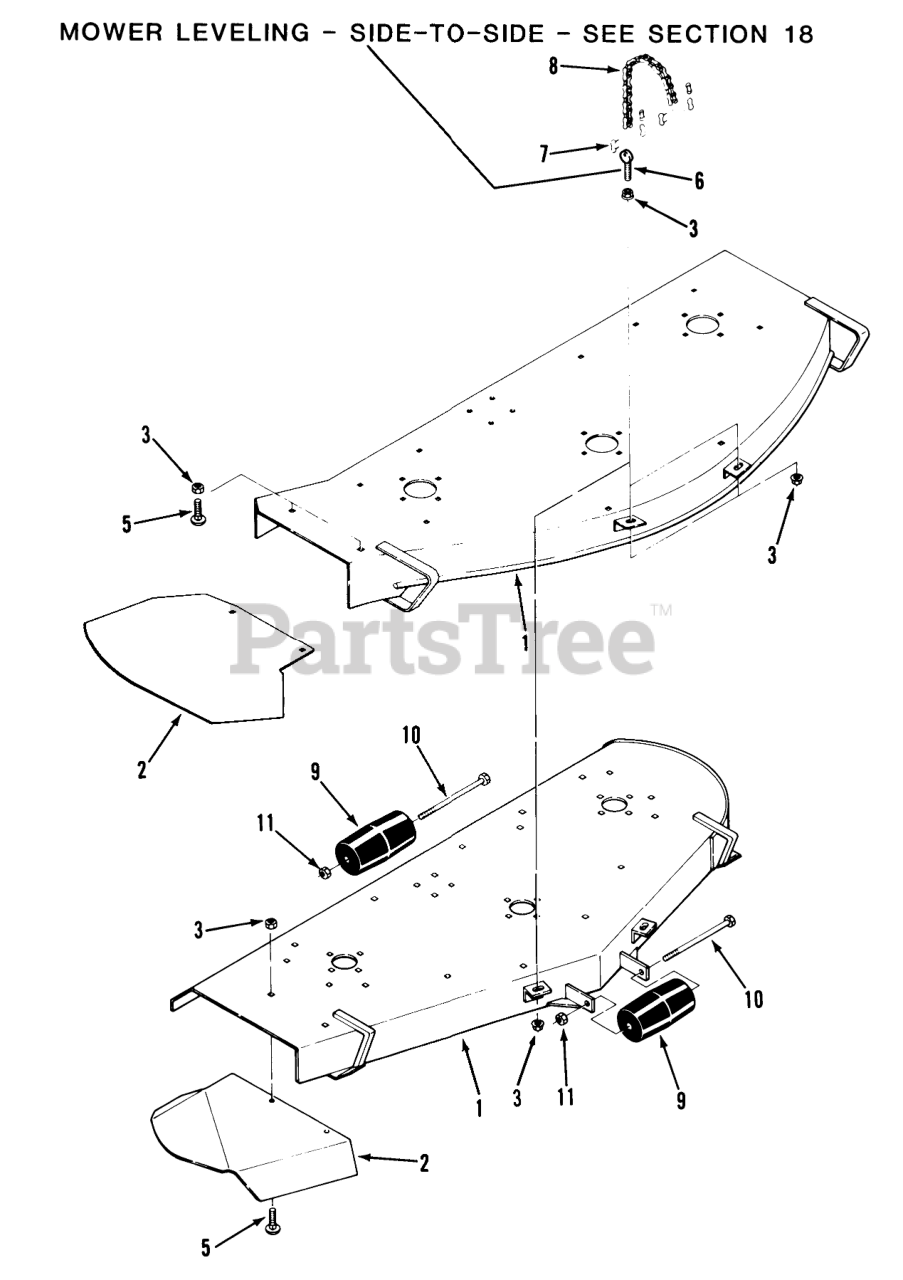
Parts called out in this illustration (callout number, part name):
1	Mower Deck
1	Mower Deck-60" Mower
2	Discharge Chute
2	Discharge Chute-60" Mower
3	NUT
5	Bolt
6	Eye Bolt 3/8-16 2 1/8
7	MASTER LINK CHAIN
8	Mower Deck Lift Chain
9	ROLLER-ANTI SCALP
10	Bolt 5/8-11 x 9 1/2-60" Mower Only
11	E.S. Nut 5/8-11
